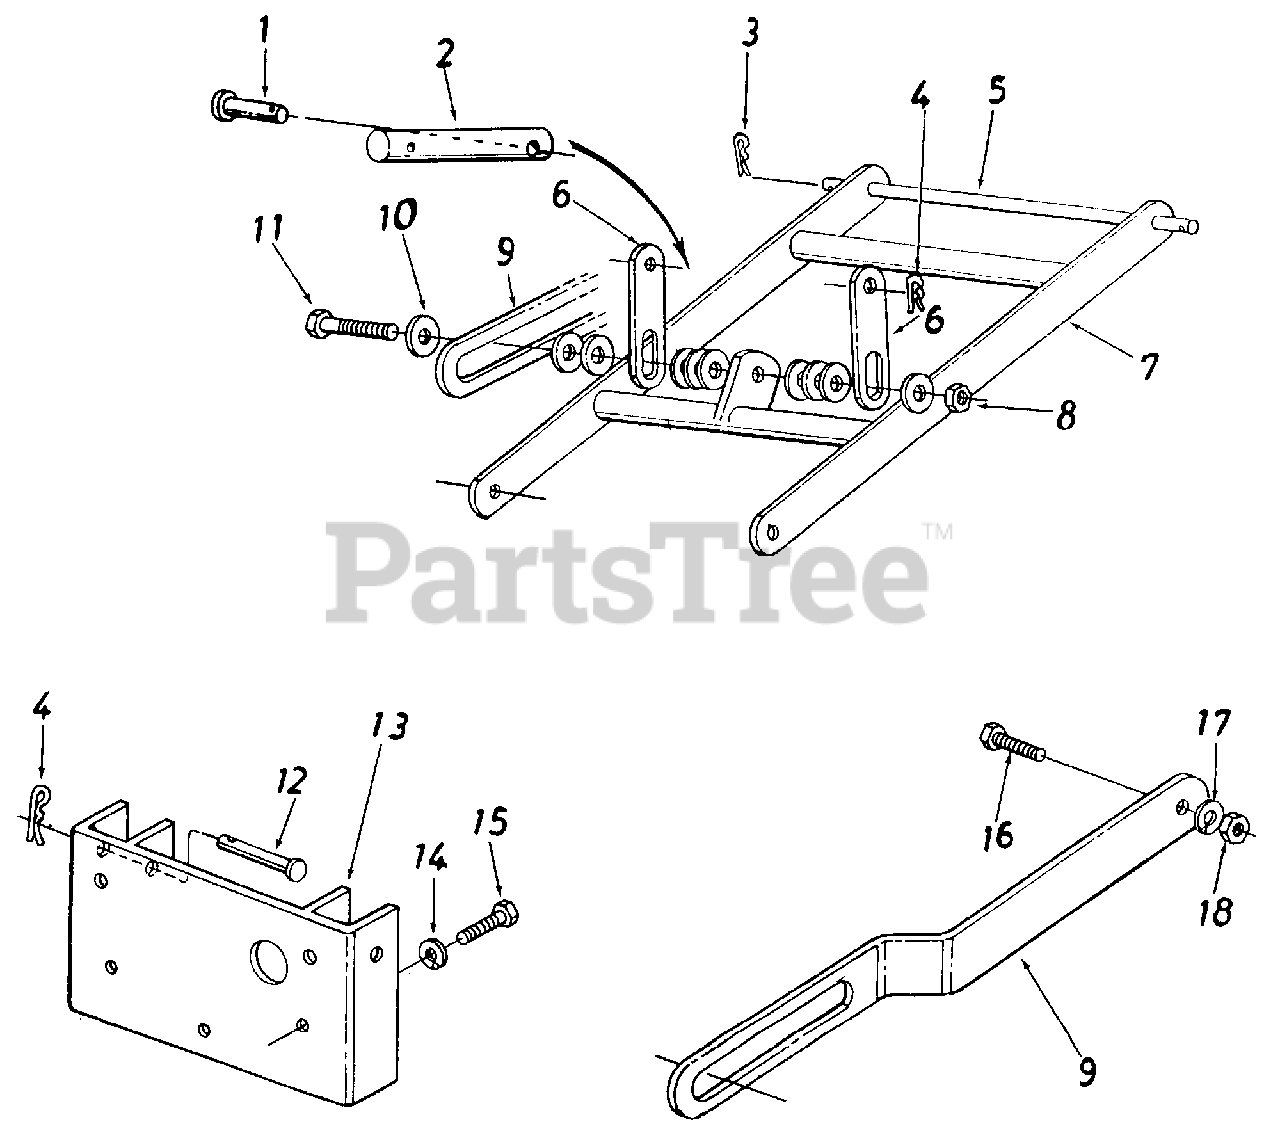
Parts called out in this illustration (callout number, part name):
1	Clevis Pin 1/2" Dia. x 2.17" Lg.
2	Hitch Shaft
3	Internal Cotter Pin
4	Hair Pin Cotter
5	Hitch Rod
7	Hitch Bar Ass'y.
8	Hex L.-Nut 1/2-13 Thd.
9	Stabilizer Link
10	Fl.-Wash. 1/2" I.D. x .93" O.D.
11	Hex Bolt 1/2-13 x 3" Lg.
12	Clevis Pin 5/8" Dia. 3-1/16" Lg.
13	Mounting Plate Ass'y.
14	L.-Wash. 3/8" I.D.
15	Hex Bolt 3/8-16 x 1.25" Lg. (Grade 5)
16	Shoulder Bolt 4.35" Dia. x .265
17	L.-Wash 5/16" I.D.
18	Hex Nut 5/16-18 Thd.
